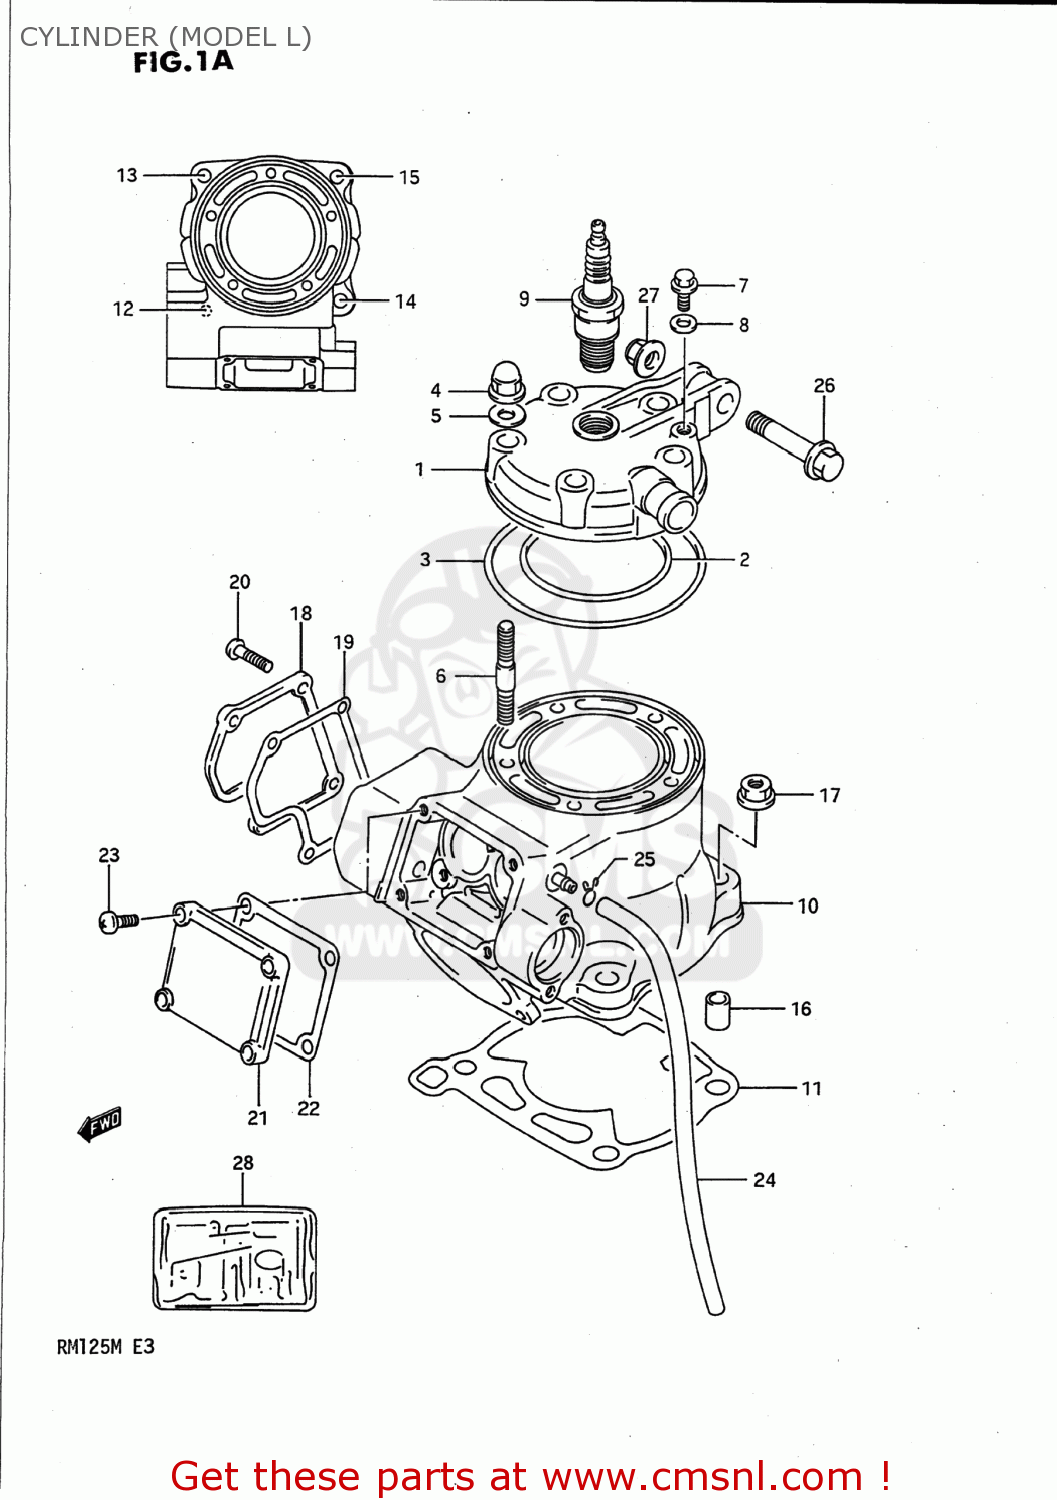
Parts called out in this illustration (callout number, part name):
1	HEAD,CYLINDER
2	O-RING,CYLINDER HEAD N
3	O-RING,CYLINDER HEAD N
4	NUT
5	GASKET(8.5X17X2.3) (NAS)
6	BOLT,CYLINDER HEAD STUD
7	UNION
8	GASKET(6.2X11X1).2 (NAS)
9	SPARK PLUG W27ES-ZU
10	CYLINDER
11	GASKET,CYLINDER (NAS)
12	STUD 8X25
13	BOLT,STUD
14	STUD BOLT
15	BOLT,STUD
16	PIN
17	NUT
18	COVER,CYLINDER NO.1
19	GASKET,CYL COVER NO.1 (NAS)
20	SCREW
21	COVER,CYLINDER NO.2
22	GASKET,CYL COVER NO.2 (NAS)
23	SCREW
24	HOSE
25	CLIP
26	BOLT(8X41)
27	NUT
28	GASKET SET (MCA)
